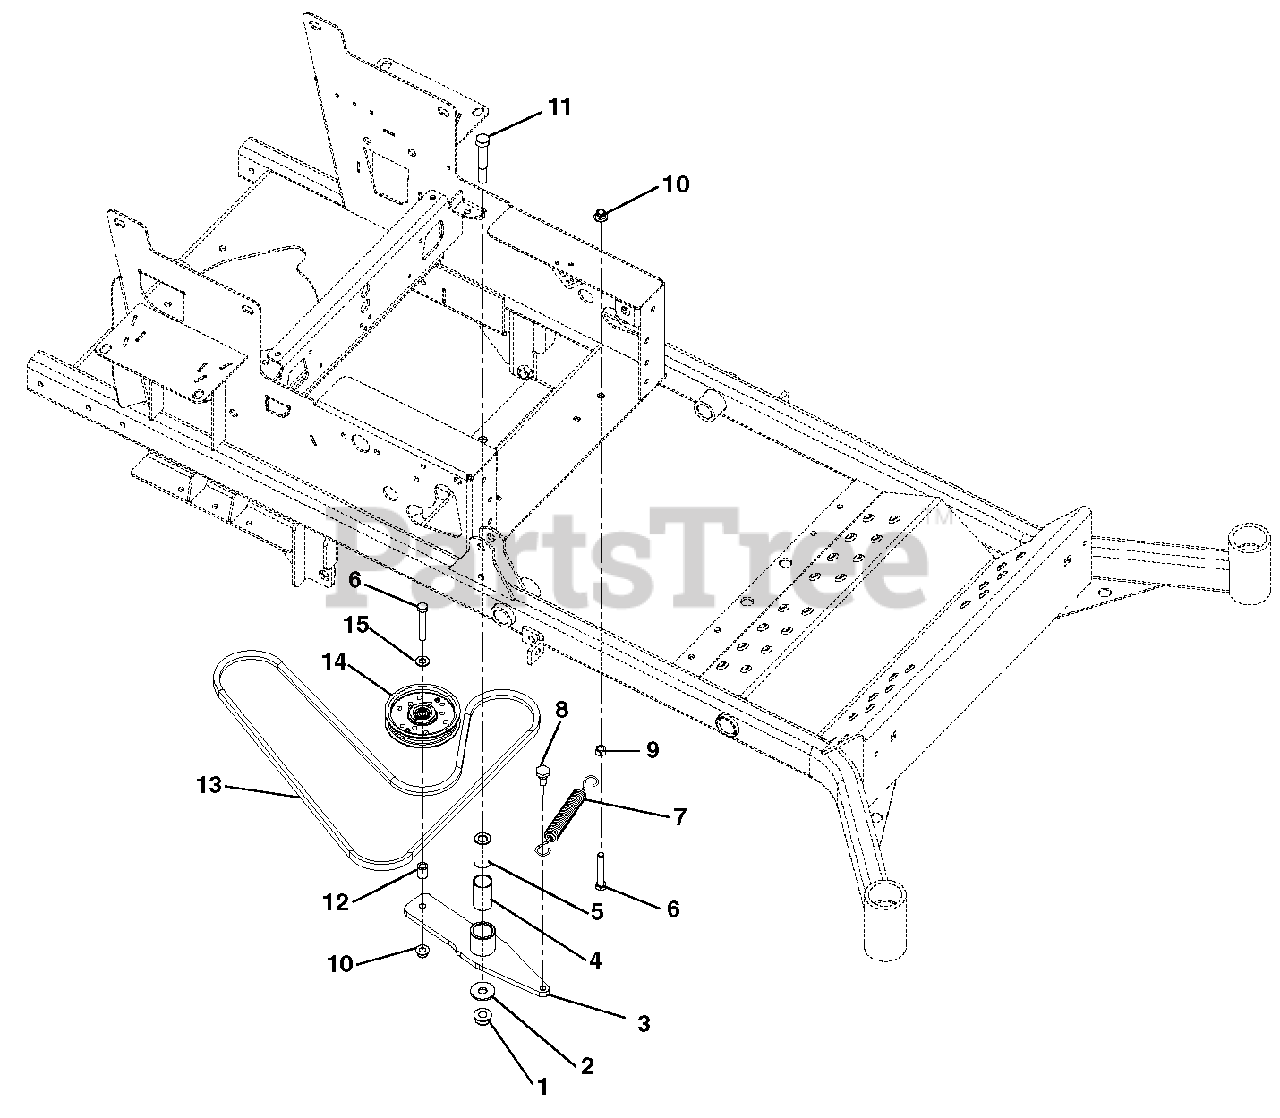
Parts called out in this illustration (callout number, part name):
1	Nut, .50-13 Nyloc Flange
2	Washer, Flat Steel .511 x 1.441 x .125
3	Weldment, Hydro Drive Idler Arm
4	Bushing, 1.00 x 1.125 x 1.936
5	Bushing, Spacer .505/.500 x .999/.996 x 2.05/2.03 Promaster
6	Bolt, Hex .38-16 x 2.50 Grade 5
7	Spring, Extension
8	Bolt, Shoulder EP .38-16 x .30 Hex
9	Nut, Hex .38-16
10	Nut, .38-16 Nyloc Flange
11	Bolt, Hex .50-13 x 3.25 Grade 5
12	Bushing, Sleeve .407 x .625 x .750
13	Belt, A 69.26 Raw Cogged
14	Idler, Flat 4.00 x .38
15	Washer, Flat-Steel .406 x .812 x .065
